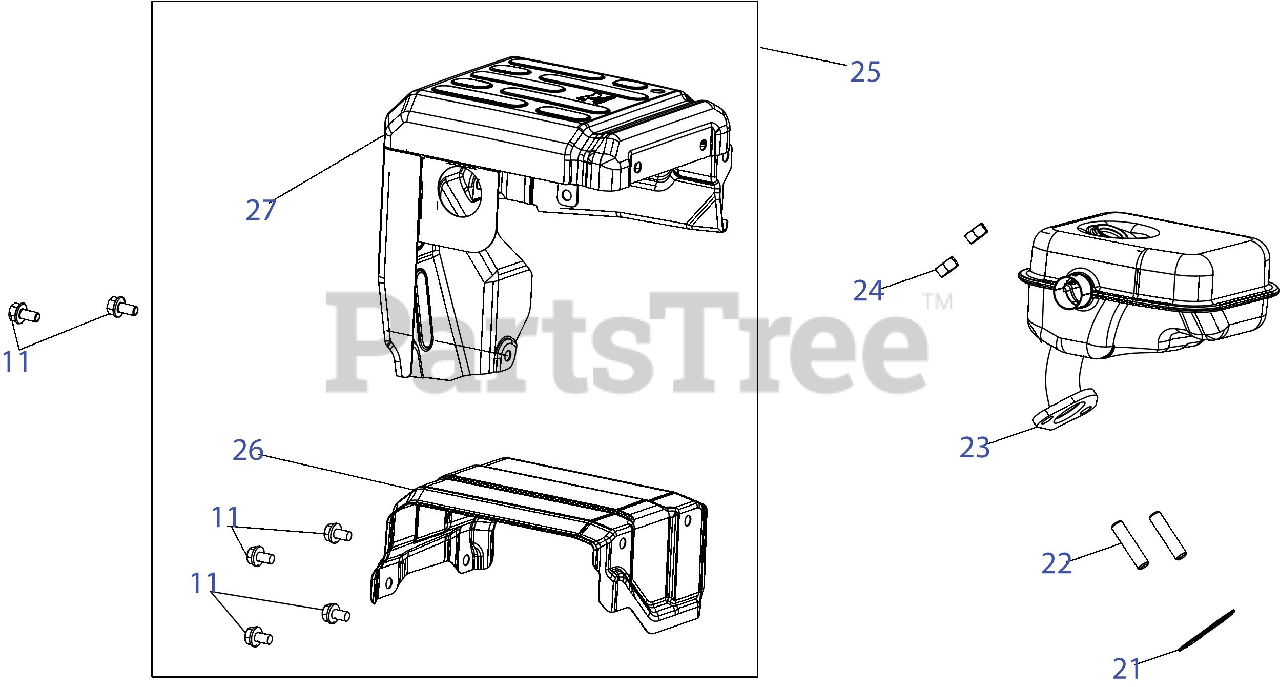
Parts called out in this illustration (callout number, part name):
11	Bolt, M6x12
21	Gasket, Muffler
22	Stud, M8x34
23	Muffler
24	Nut, M8
25	Muffler Guard
26	Muffler Inner Shield
27	Muffler Shield
